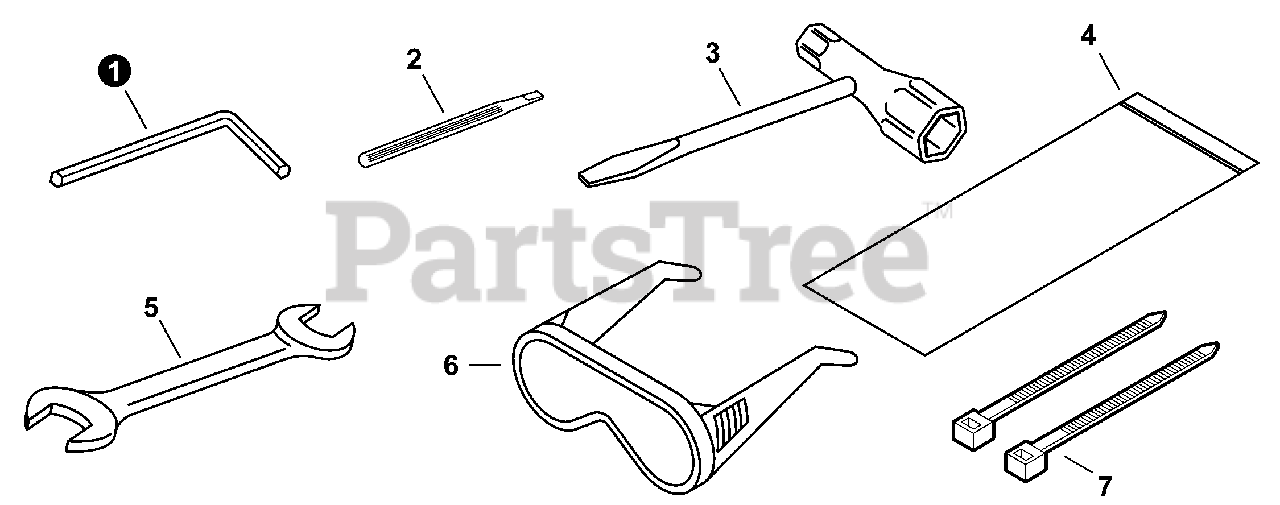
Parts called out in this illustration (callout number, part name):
1	WRENCH, ALLEN 4MM
2	SCREWDRIVER, PLASTIC
3	T-WRENCH 13×19mm
4	BAG, TOOL
5	SPANNER 8×10
6	GLASSES, SAFETY
7	TIE, CABLE
